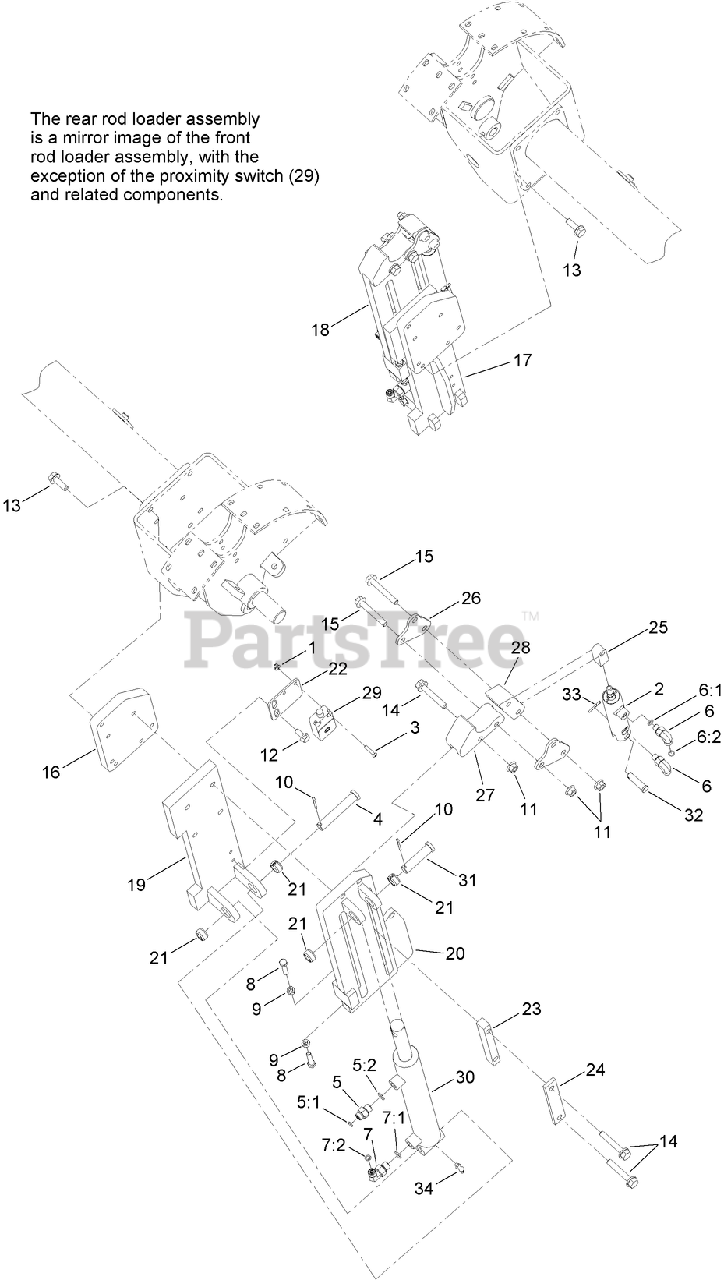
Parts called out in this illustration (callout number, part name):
1	NUT-HF
2	HYD CYLINDER ASM
3	SCREW-HSH
4	PIN-CLEVIS
5	FITTING-STRAIGHT
5:1	O-RING
5:2	O-RING
6	FITTING-90 DEG
6:1	O-RING
6:2	O-RING
7	FITTING-ELBOW 90
7:1	O-RING
7:2	O-RING
8	SCREW-HH
9	NUT-HEX
10	PIN-COTTER
11	NUT-LOCK, NI
12	SCREW-HHF
13	SCREW-HHF
14	SCREW-HHF
15	SCREW-HHF
16	PLATE-SPACER
17	ARM-EXTENSION
18	EXTENSION-SLIDER, REAR
19	ARM-EXTENSION
20	EXTENSION-SLIDER, FRONT
21	BUSHING-SPRING
22	BRACKET-SENSOR, EXTENSION ARM
23	GUIDE-EXTENSION ARM
24	CAP-GUIDE, EXTENSION ARM
25	ROD-EYE, CYLINDER
26	PLATE-GRIPPER, ROTATE
27	INSERT-GRIPPER, FIXED
28	INSERT-GRIPPER, ROTATE
29	SWITCH-PROXIMITY
30	HYD CYLINDER ASM
31	PIN-CLEVIS
32	PIN-CLEVIS
33	PIN-COTTER
34	FITTING-GREASE, 90 DEG
